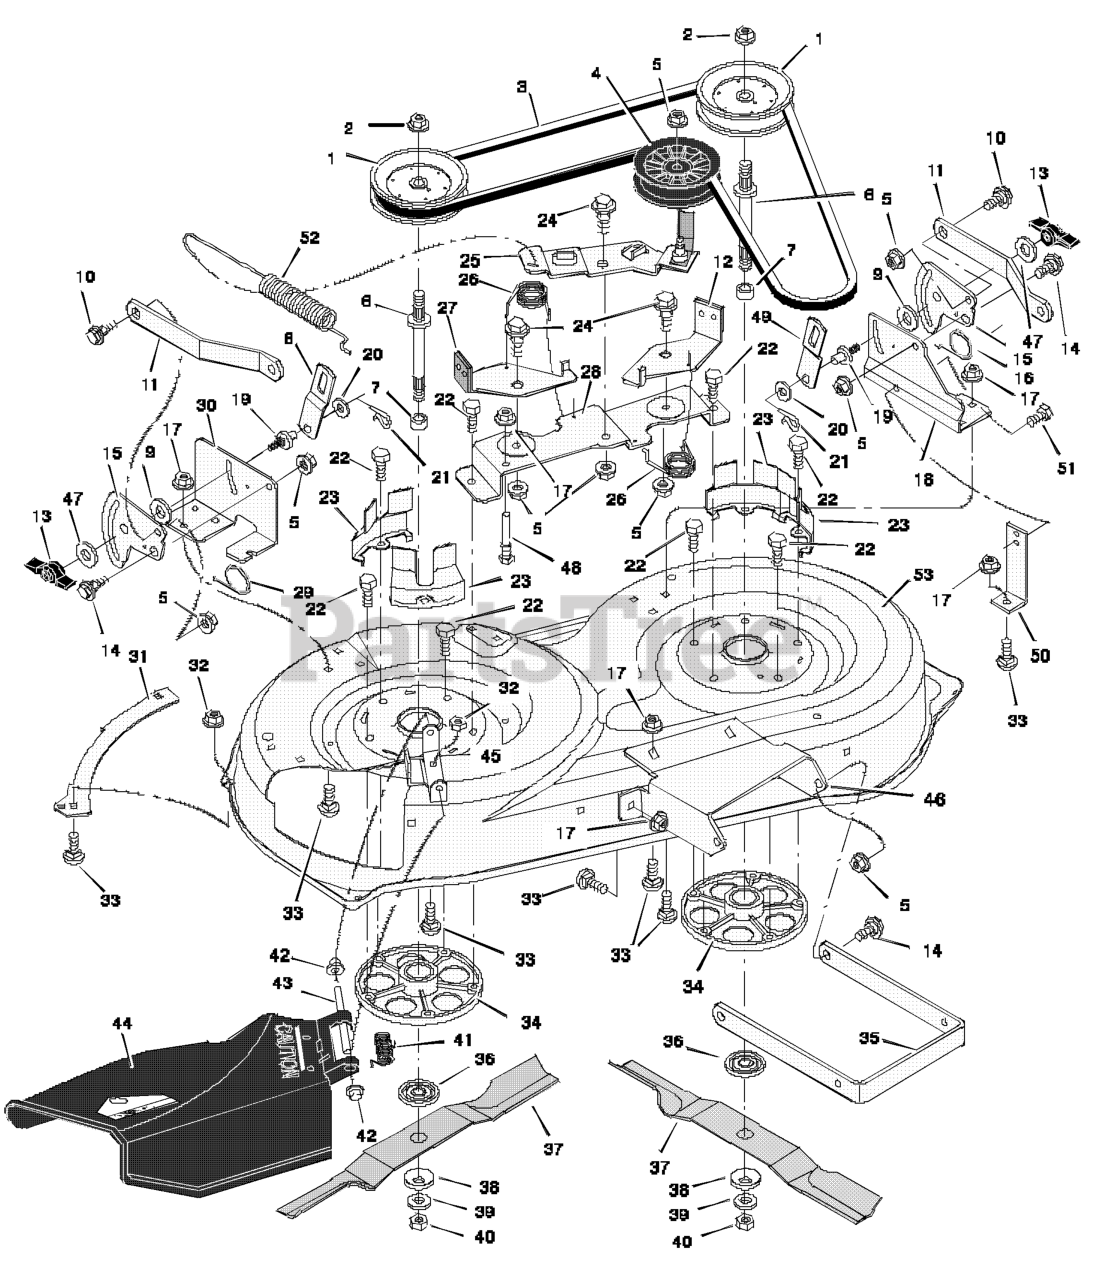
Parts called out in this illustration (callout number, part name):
1	Pulley, Jackshaft
2	Nut, Hex
3	Belt, Mower Drive
4	Pulley, Idler
5	Nut, Flange
6	Jackshaft
8	Link, Right Lift
9	Pad, Friction
10	Bolt, Shoulder
11	Bracket, Suspension
12	Pad Assembly, Left Brake
13	Knob
14	Bolt, Shoulder
15	Plate, Suspension
17	Nut, Flange
18	Bracket, Suspension
19	Pin, Hanger
21	Pin, Cotter
22	Bolt
23	Cover, Pulley
24	Bolt, Shoulder
25	Arm, Idler
26	Spring
27	Pad Assembly, Right Brake
28	Bracket Assembly, Brake
30	Bracket, Suspension
31	Plate
32	Nut, Flange
33	Bolt, Carriage
34	Mandrell
35	Bracket, Suspension
36	Adapter, Blade
42	Cap, Push On
43	Rod, Pivot
44	Deflector
45	Bracket, Deflector
46	Bracket, Front Hanger
48	Guide, Belt
49	Link, Left Lift
50	Bracket, Support
52	Spring, Extension
53	Housing, Blade
